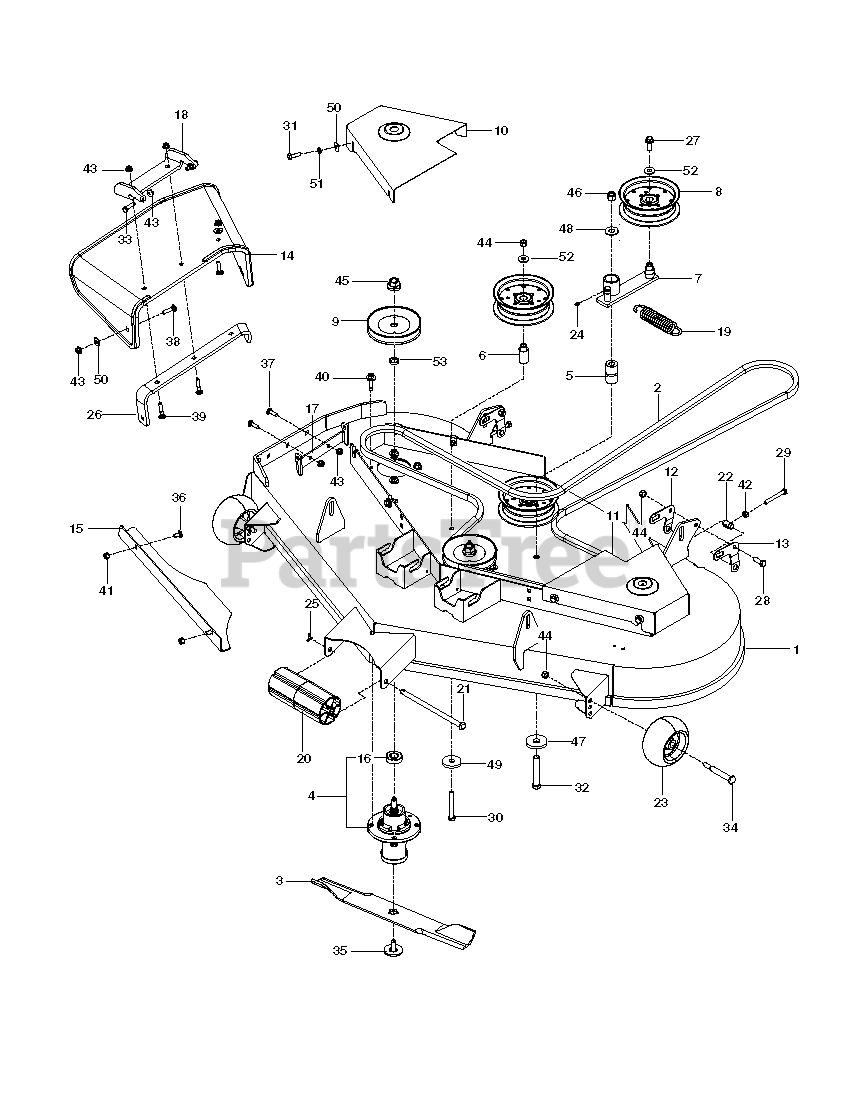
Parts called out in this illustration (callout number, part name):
1	DECK MZT 52 W/SFTY DECALS.ORNG
2	BELT, B, 148.5
3	BLADE, 18"
4	MANDREL ASM, CAST IRON
5	PIVOT BUSHING
6	IDLER BUSHING
8	PULLEY, IDLER
9	PULLEY MANDREL
10	BELT SHIELD, RIGHT 52, ORG
11	BELT SHIELD, LEFT 52, ORG
12	PITCH, ADJUST, RT
13	PITCH, ADJUST, LT
14	CHUTE, RUBBER DISCHARGE 52/61"
15	CONFINEMENT PLATE, 52"
16	BEARING, BALL
17	BRACKET MZ CHUTE
18	PIVOT BRACKET - CHUTE
19	SPRING - TORSION
20	NOSE ROLLER 48"
21	ROD.ROLLER.NOSE.NARROW.48"
22	TRUNION, PITCH
23	GAUGE WHEEL
24	ZERK
25	RP_COTTER PIN 1/8 X 3/4
26	BRKT, REINF - CHUTE 52/61"
27	4CS 3/8C X 1 SERRATED HEAD
28	HCS 3/8-16X1.GRD.5.ZD
29	HCS 5/16-18 X 2 1/2 TPBLT
30	HCS 3/8C X 3
31	HCS 5/16C X 1
32	HCS 1/2C X 3 1/4
33	HCS 5/16C X 1 1/4
34	SHOULDER BOLT 1/2X2-5/8 ZD SPE
35	BOLT.WASHER.ASM.7/16-2
36	CARRIAGE BOLT 5/16C X 5/8"
37	RHSSNB 5/16C X 1.0
38	BOLT, CARRIAGE 5/16X1-1/4
39	RHSNB 5/16-18 X 1-1/2 GR 5 ZD
40	WASHER HEAD SCREW
41	NUT 5/16 NYLOC
42	NUT 5/16C HEX
43	5/16-18 NYLOC FLANGE NUT
44	NUT 3/8-16 NYLOC
45	LOCKNUT - 9/16
46	RP NUT 1/2-13 HEX NYLOC ZD
47	WASHER, SUPPORT
48	WASHER 1/2 FLAT
49	SPINDLE WASHER
50	WASHER 5/16 FLAT
51	WASHER 5/16 LOCK
52	RP WASHER 3/8 FLAT
53	WASHER-SPACER
